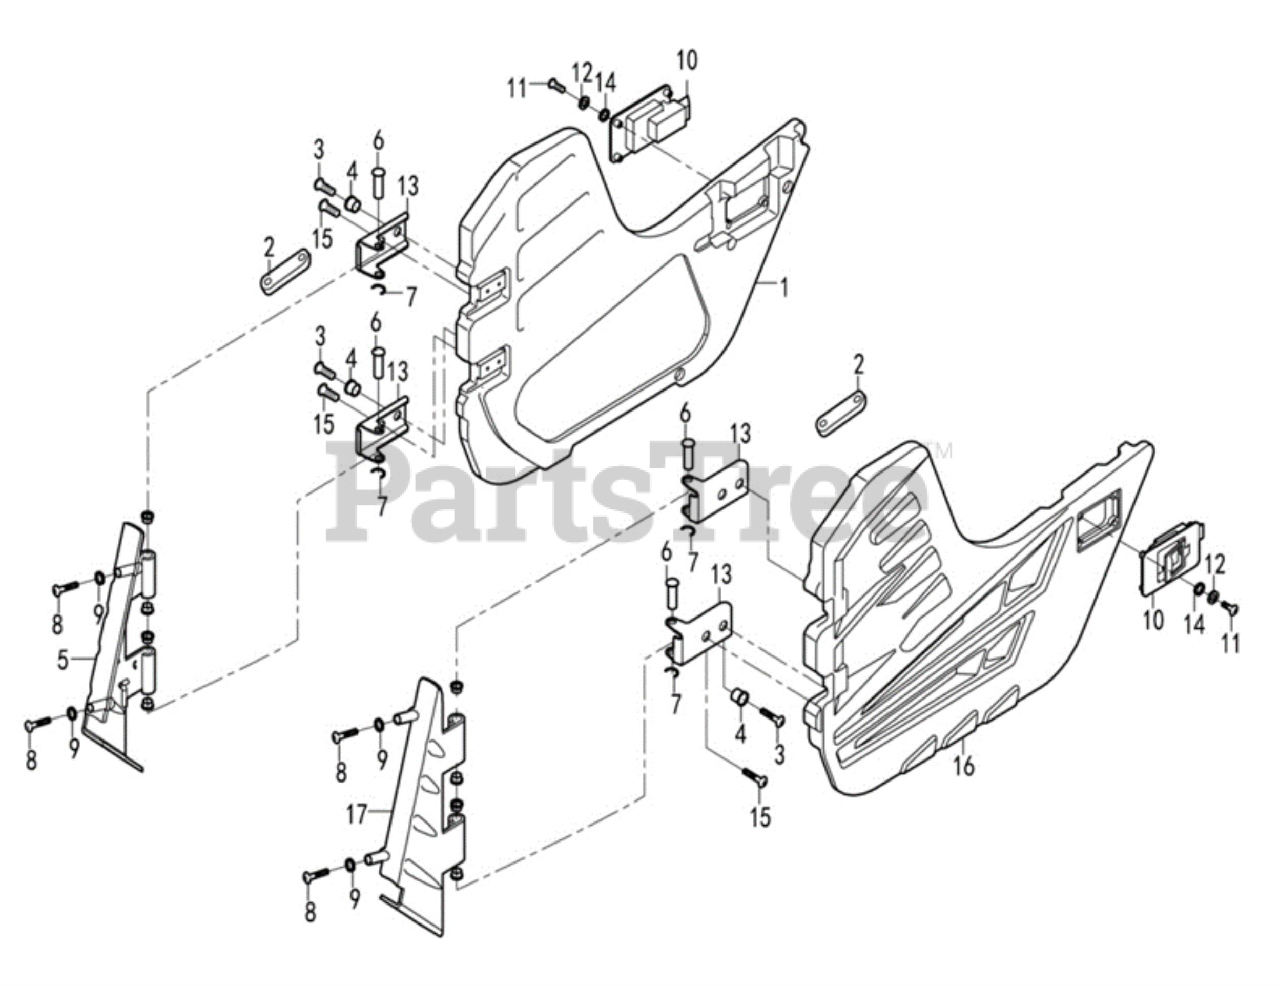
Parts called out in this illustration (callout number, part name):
1	vehicle door ?R?
2	Vehicle Door Drawstring
3	Cross Large Plate Head Screw M6X16
4	Turnup Liner 6.5X9X22X6.5
5	Mounting Plate Assy II , Vehicle Door
7	Split Washer 8X1
8	Inner Hex Spherical Step Nut M8
9	Curved Washer
10	Door Locker
11	Cross Plate Head Tapping Screw M5X12
12	Spring Washer-8
13	Door Hinge
14	Flat Washer 5
15	Cross Plate Head Screw M6X8
16	Vehicle door ?L?
17	Mounting Plate Assy I , Vehicle Door
